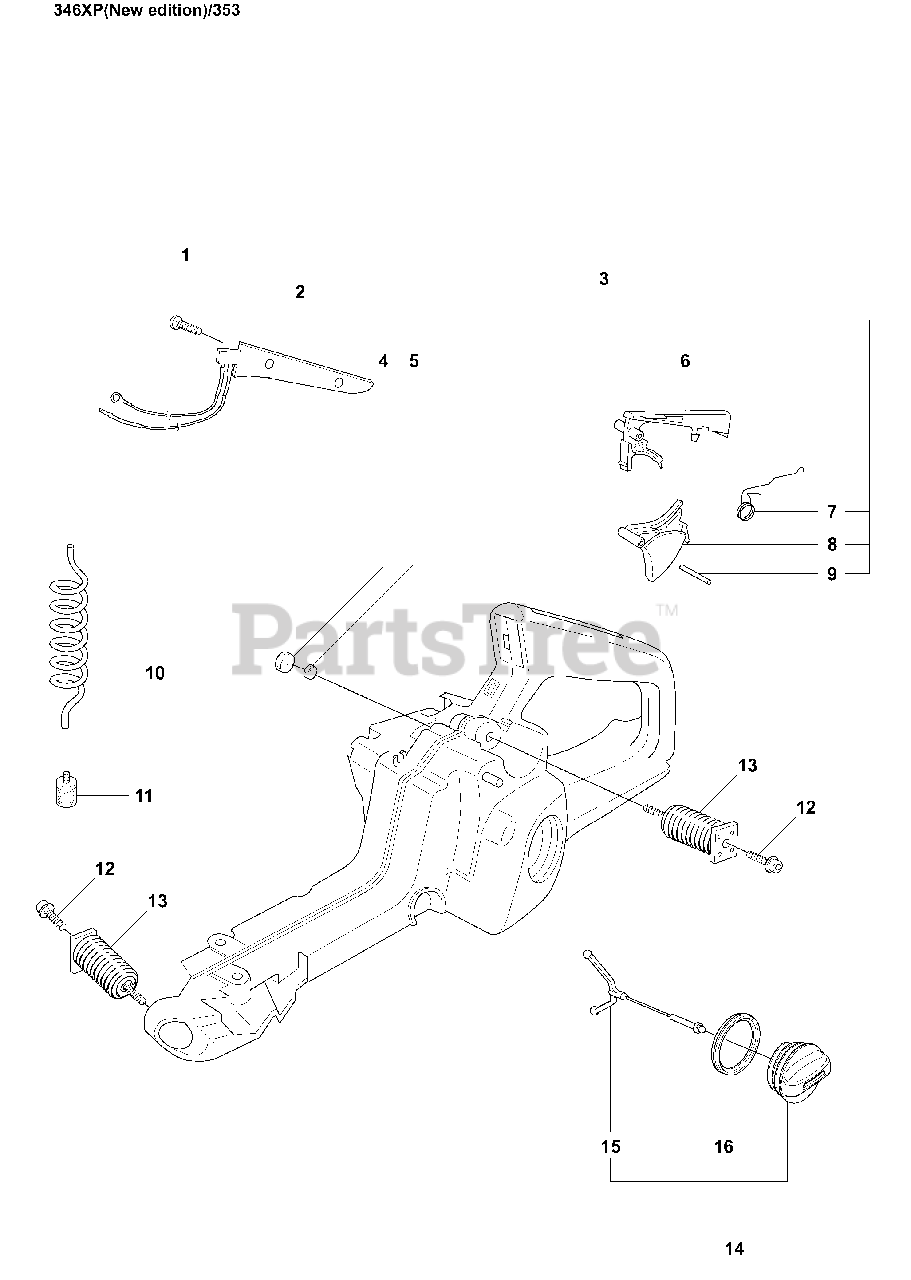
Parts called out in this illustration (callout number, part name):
1	SCREW
2	HANDLE CIRCUIT
4	FILTER PLUG
5	VALVE PLUG
6	THROTTLE LOCK
10	FUEL HOSE
11	FUEL FILTER
13	VIBRATION ABSORBER
14	TANK CAP
16	SEALING
